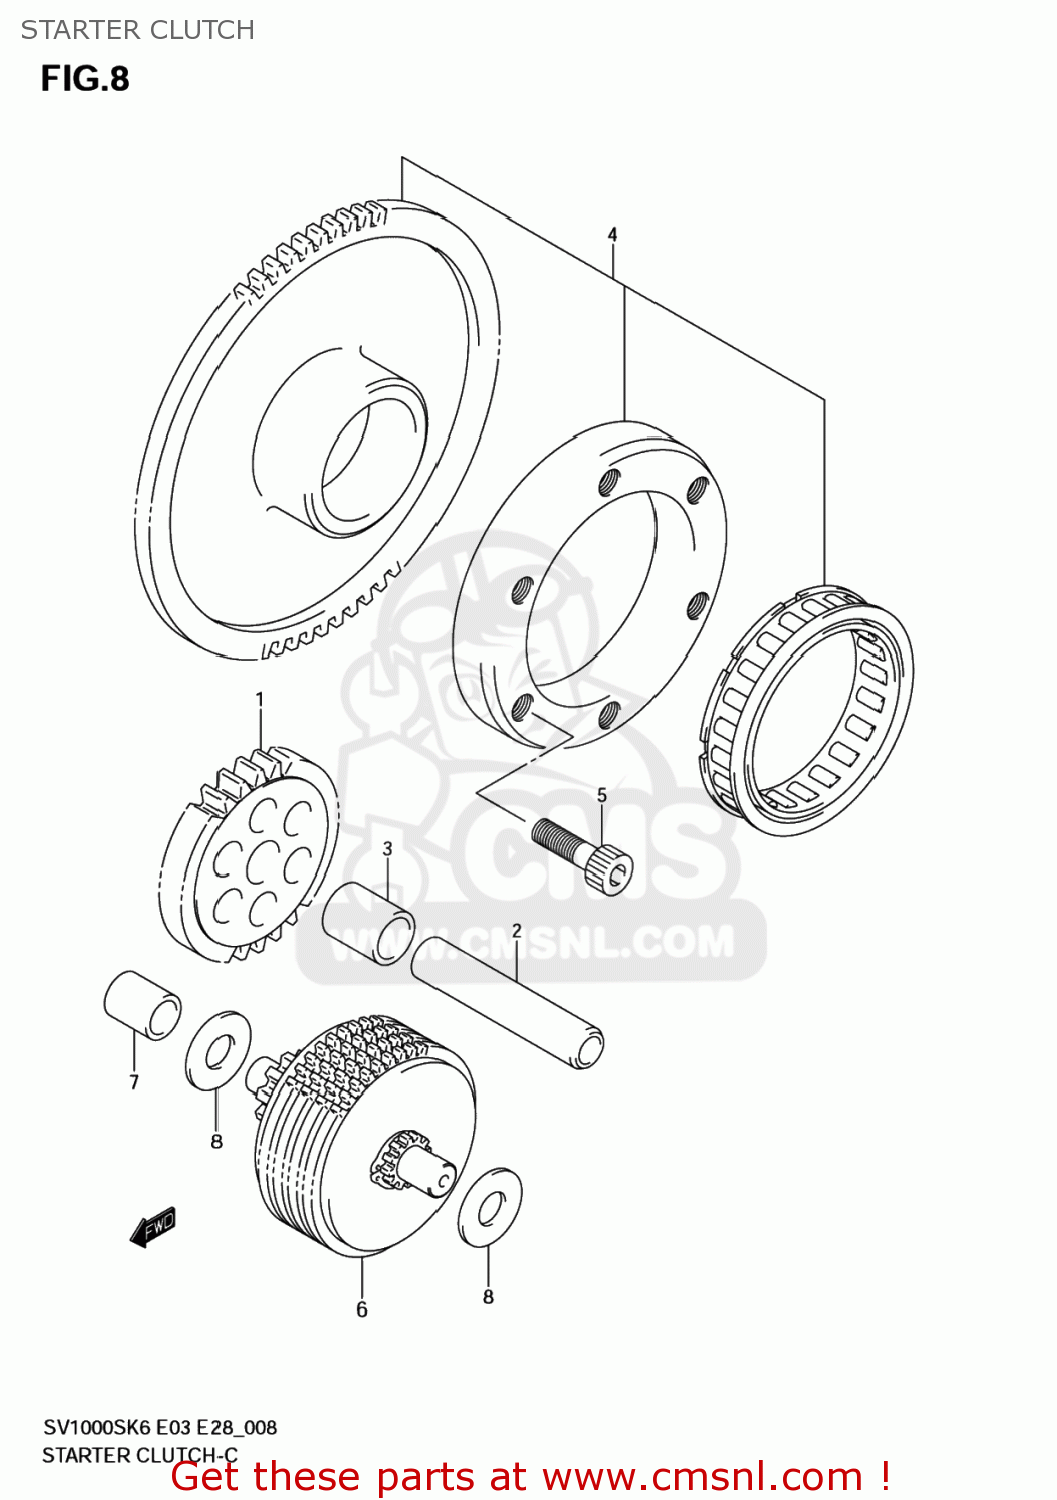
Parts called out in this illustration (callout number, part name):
1	GEAR,STARTER IDLE NO.2
2	PIN(7X12X50.5)
3	SPACER(12.5X19X17.5)
4	CLUTCH SET,STARTER
5	BOLT(8X20)
6	LIMITER ASSY, STARTER IDLE
7	BUSH,LIMITER GEAR SHAFT
8	WASHER
